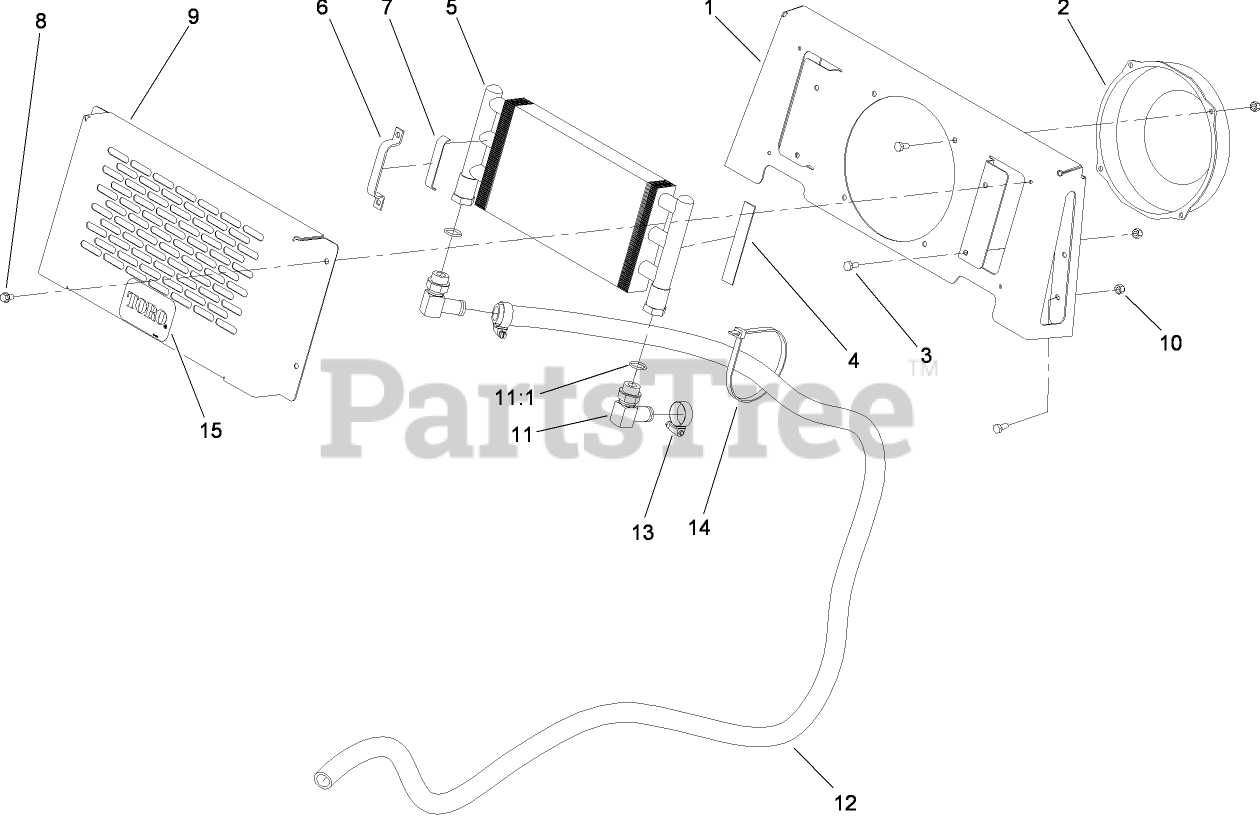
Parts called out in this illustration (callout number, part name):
1	BRACKET-FAN
3	SCREW-HH
4	PAD-FOOTREST
5	EXCHANGER-HEAT
6	SUPPORT-COOLER
7	PAD-SUPPORT
8	SCREW-THD FRM,HWH
9	BRACKET-COVER, COOLER
10	NUT-LOCK, NI
11	FITTING
11:1	O-RING
12	HOSE-RETURN
13	CLAMP-HOSE
14	TIE-CABLE
15	DECAL
